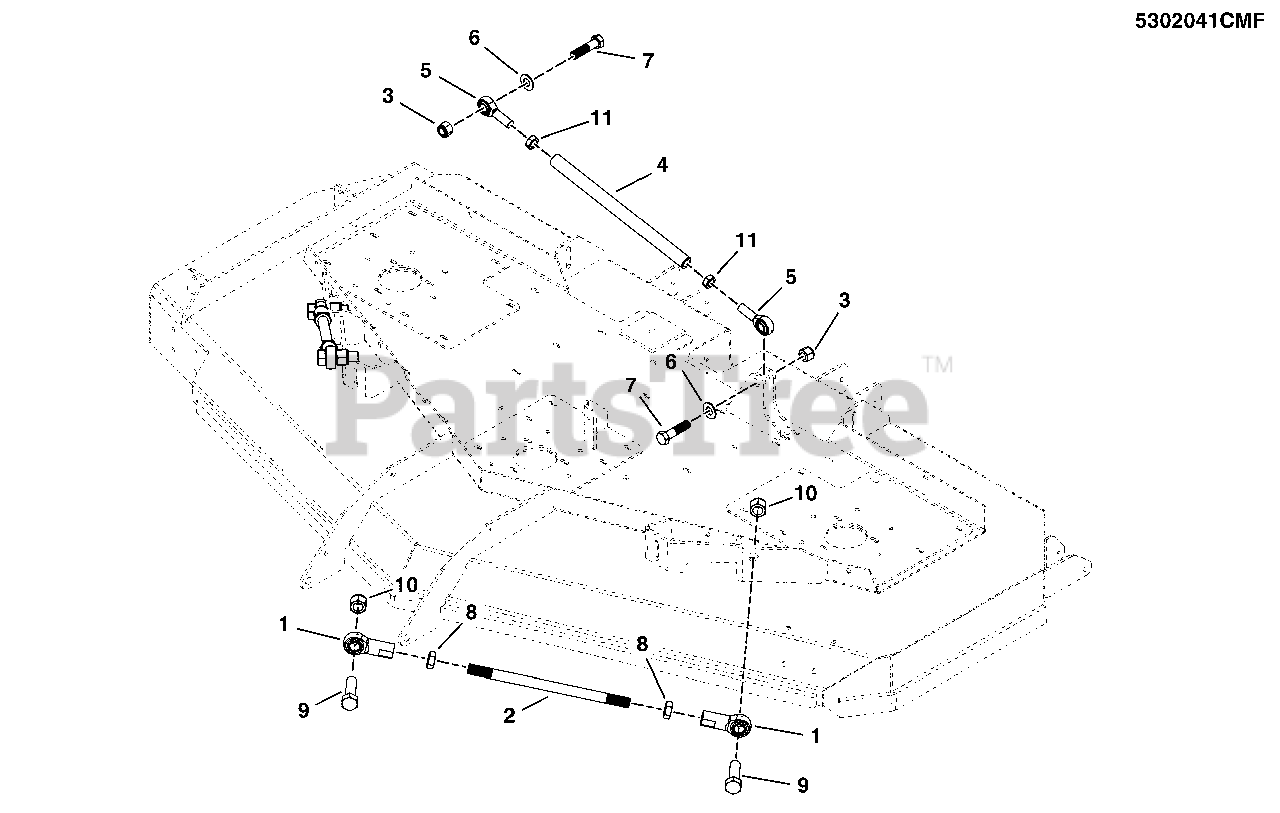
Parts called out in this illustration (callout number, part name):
1	BALL JOINT, 3/4-16, FEMALE
2	ROD, 3/4-16 X 12.31 - BLK
3	NUT,5/8-11 HEX NYLON LOCK
4	SHAFT, DECK STABILIZER, 14.50, CZ
5	BALL JOINT, 5/8-18, MALE
6	WASHER, 5/8 SAE
7	BOLT, 5/8-11 X 2-1/2 GD5, CZ
8	NUT, 3/4-16 HEX JAM
9	BOLT, 3/4-16 X 2-1/2 YZ GD5
10	NUT, 3/4-16 HEX NYLON LOCK
11	NUT, 5/8-18, HEX JAM
